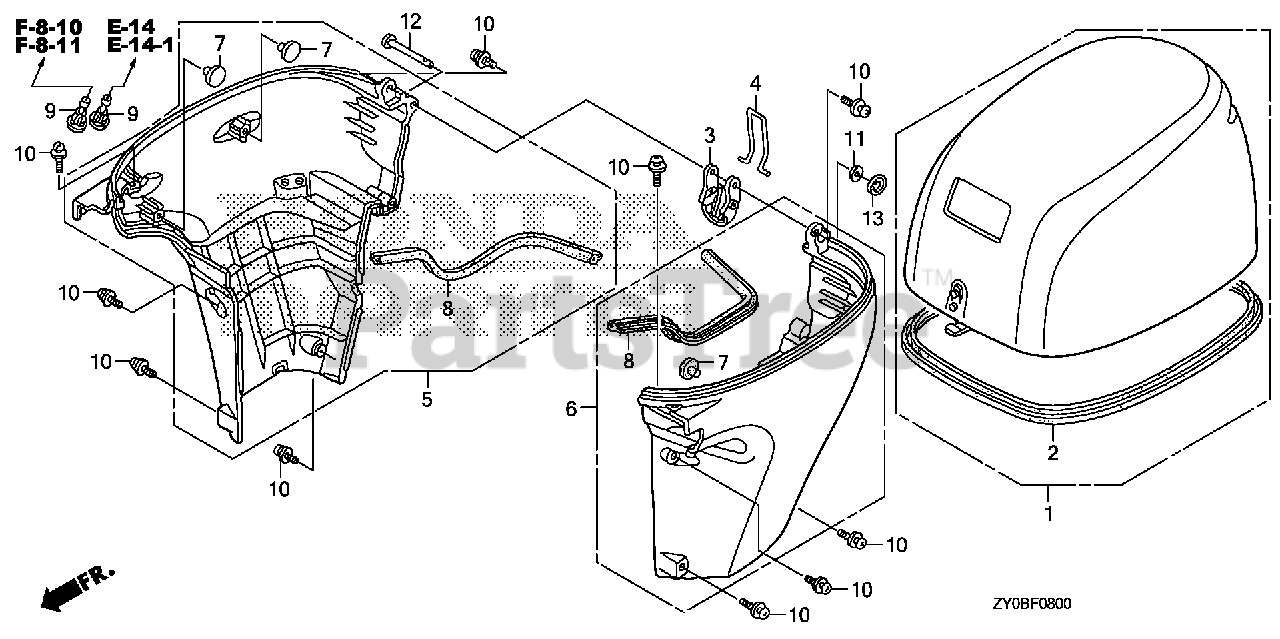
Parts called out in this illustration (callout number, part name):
1	COVER, ENGINE *NH282MU* (OYSTER SILVER METALLIC-U)
2	SEAL, ENGINE COVER
3	LEVER, FASTENER
4	WIRE, FASTENER (3.2)
5	COVER, R. ENGINE (LOWER) *NH282MU* (OYSTER SILVER METALLIC-U)
6	COVER, L. ENGINE (LOWER) *NH282MU* (OYSTER SILVER METALLIC-U)
7	RUBBER, CUSHION
8	SEAL, COVER (LOWER)
9	GROMMET, WATER CHECK
10	BOLT-WASHER, SOCKET (5X10)
11	WASHER, PLAIN (5MM)
12	PIN (5X47)
13	RING, STOPPER
